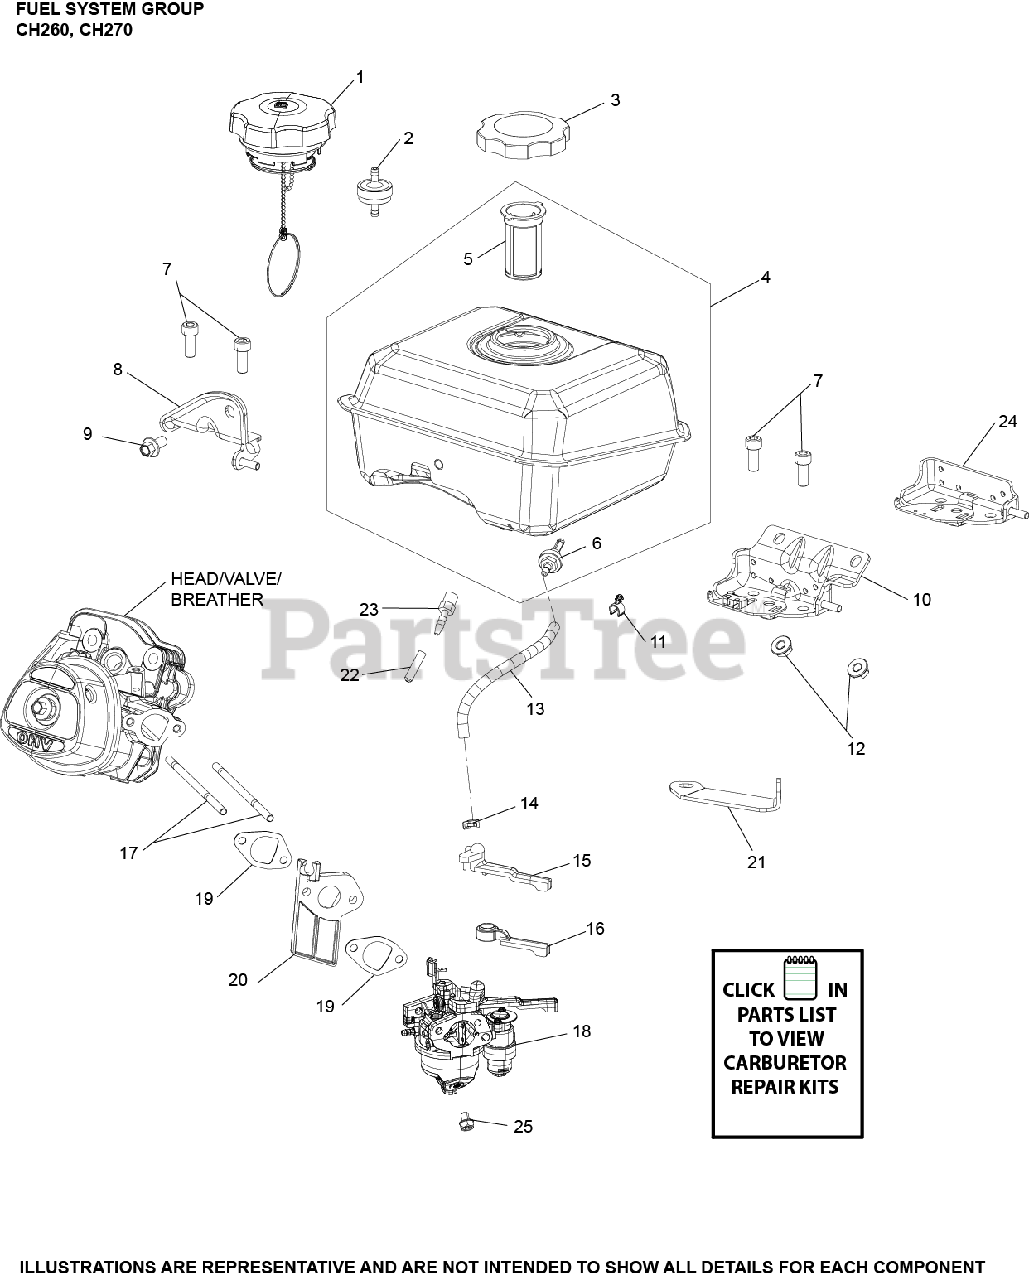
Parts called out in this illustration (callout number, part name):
3	CAP, FUEL TANK
4	TANK, ASSY FUEL
5	FILTER, FUEL TANK
6	FITTING, FUEL ASSY
8	BRACKET ASSY, FUEL TANK
11	CLIP, FUEL HOSE
13	LINE, FUEL (10"-CUT TO LENGTH)
14	CLAMP, FUEL LINE
15	LEVER, CHOKE
16	LEVER, FUEL SHUTOFF
17	STUD, CARBURETOR
18	KIT, CARBURETOR ASSEMBLY
25	SCREW, BOWL DRAIN (CKY)
29	KIT, FUEL SCREEN
